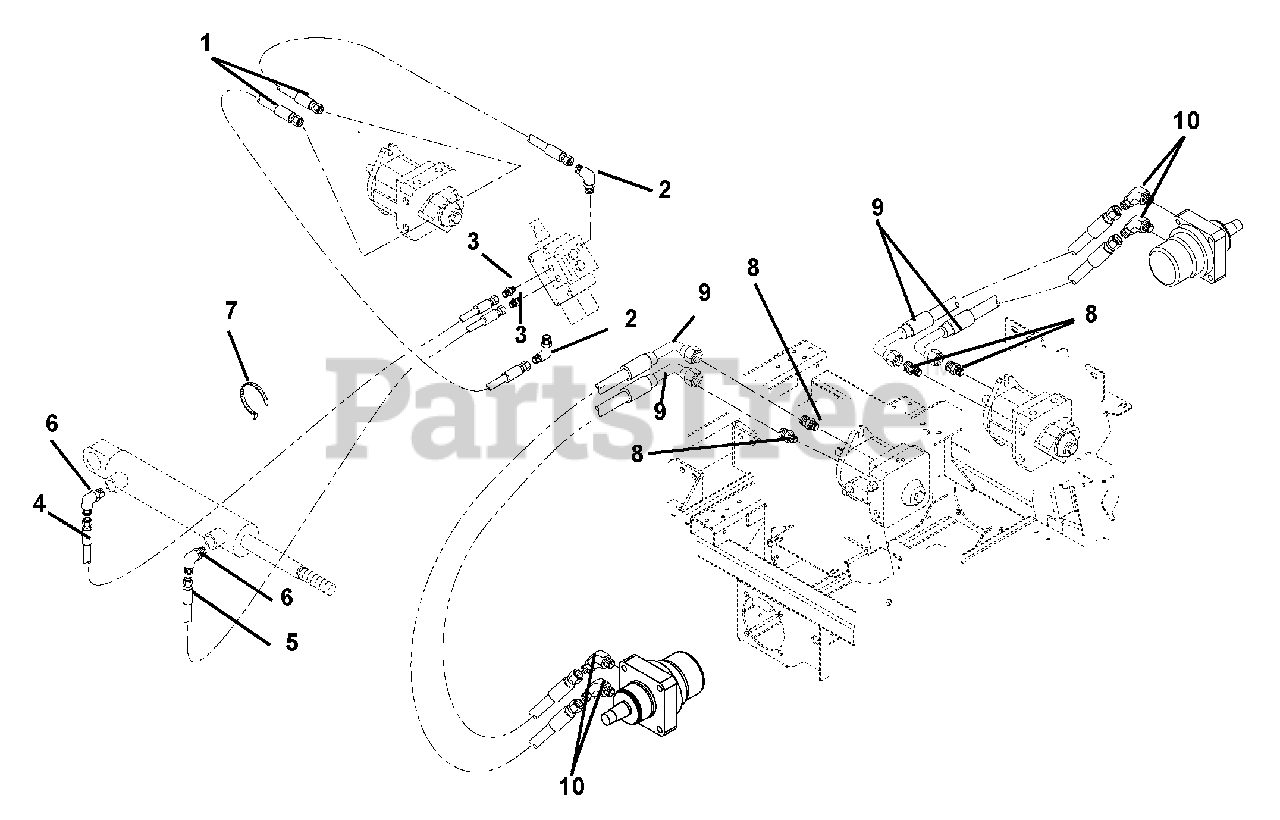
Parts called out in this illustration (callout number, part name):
1	Hose, Hydraulic
2	Hydraulic, Fitting Elbow
3	Adapter
4	Hose, Hydraulic
5	Hose, Hydraulic
6	Fitting, Hydraulic
7	Cable Tie
8	Adapter, Face Seal 8 x 8 .50 O-Ring
9	Hose, Hydraulic .50
10	Adapter-Hydraulic Steel .875 to .75
